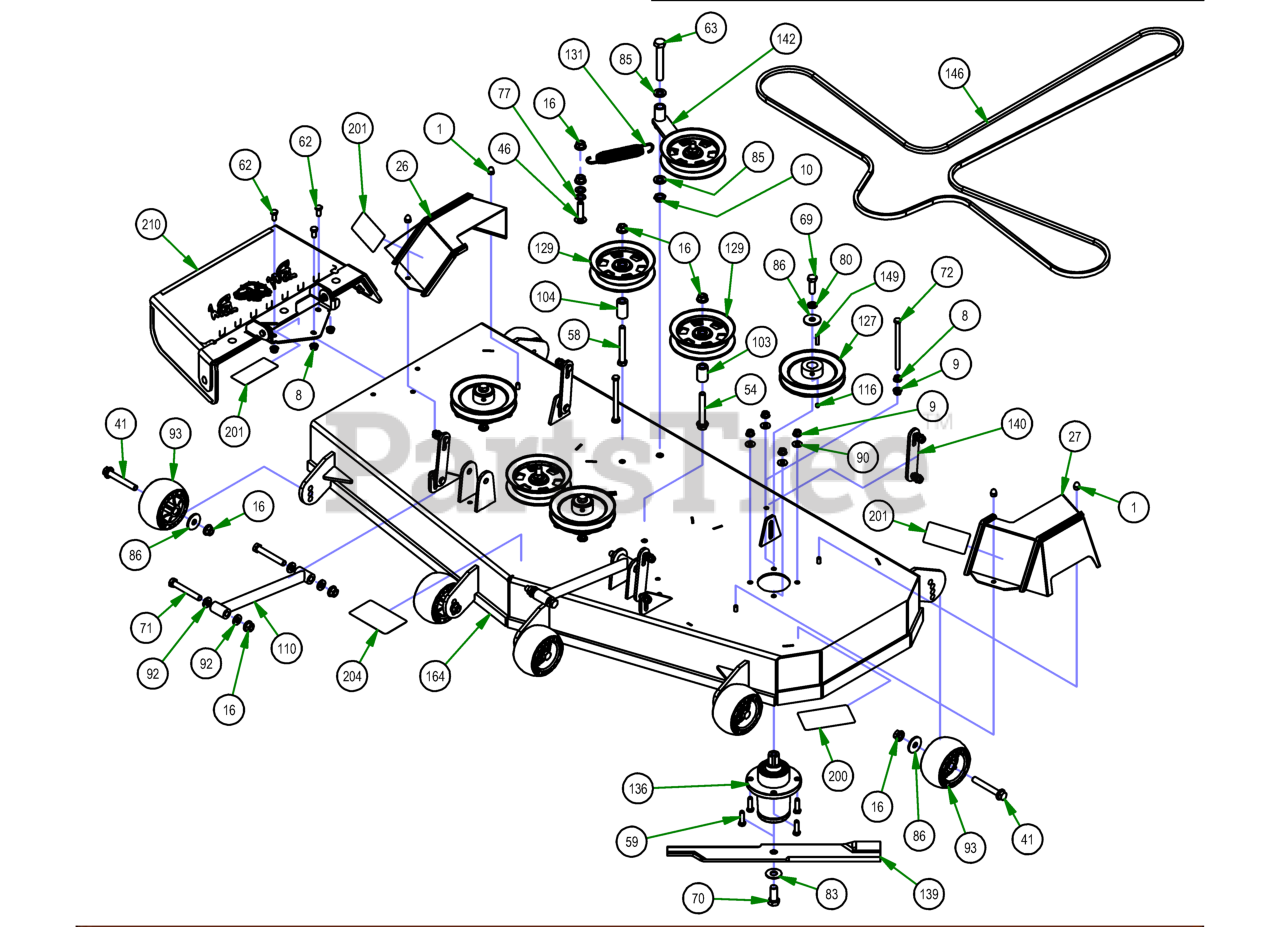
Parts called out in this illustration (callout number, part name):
1	5/16-18 ACORN NUT HIGH-CROWN ZC
8	3/8-16 HEX SERRATED FLANGE NUT HARD/ZINC
9	3/8-16 NYLON INSERT FLANGE LOCKNUT (GR.F) ZINC
10	5/8-11 NYLON INSERT JAM LOCKNUT ZINC
16	1/2-13 NYLON INSERT FLANGE LOCKNUT ZINC
26	2021 Maverick 54”/60” RH Pulley Cover
27	2021 Maverick 54”/60” LH Pulley Cover
41	1/2-13 X 90MM HEX FLANGE BOLT W/SHOULDER (GR.8) ZINC
46	1/2-13 X 2 CARRIAGE BOLT ZINC
54	1/2-13 X 3-1/2 HEX FLANGE BOLT (GR.8) ZINC
58	1/2-13 X 4 HEX CAP SCREW (GR.8) ZINC YELLOW
59	3/8-16 X 1-1/4 HEX CAP SCREW (GR.5) ZINC
62	3/8-16 X 3/4 HEX CAP SCREW (GR.5) ZINC
63	5/8-11 X 4 HEX CAP SCREW (GR.8) ZINC YELLOW
69	1/2-20 X 1-1/2 HEX CAP SCREW (GR.5) ZINC
70	5/8-18 X 1-1/2 HEX CAP SCREW (GR.8) ZINC YELLOW
71	1/2-13 X 3-1/2 HEX CAP SCREW (GR.5) ZINC
72	3/8-16 X 5-1/2 HEX CAP SCREW (GR.5) ZINC
77	.517 SQ WDTH ID X .937 OD X .060 THICK F/W PHOS/OIL
80	1/2 SPLIT LOCKWASHER (GR.8) ZINC/YELLOW
83	5/8 USS FLAT WASHER (1-3/4" OD) GR.8 ZINC YELLOW
85	.635 ID X 1.120 OD X .140 THICK FLAT WASHER NYLON
86	1/2 BELLEVILLE WASHER (1-5/8 OD X .140 THK) ZINC
90	5/16 USS FLAT WASHER (7/8 OD) ZINC
92	.505 ID X 1.000 OD X .125 THICK FLAT WASHER NYLON
93	Deck Wheel
103	.502 ID X .750 OD X 1.500 Long Spacer
104	1 3/4" Pulley Spacer
110	MZ/ZT Deck Locator
116	5/16-24 X 1/4 SOCKET SET SCREW (CUP PT) PLAIN
127	6 1/4" Drive Pulley
129	5-3/4 Idler Pulley
131	Deck Idler Spring
136	Spindle Assembly
139	60" High Lift Fusion Blade
140	Deck Hanger Assembly
142	2017 MZ/ZT Deck Idler Assembly
149	1/4 X 1 SQ MACHINERY KEY 1018 STL PLN
164	2017 60" ZT Deck Welded Assembly
200	2018 60" Deck Decal
201	Danger Decal-Spindle/Discharge
204	Deck Belt Route Decal
210	Discharge Chute Assembly
